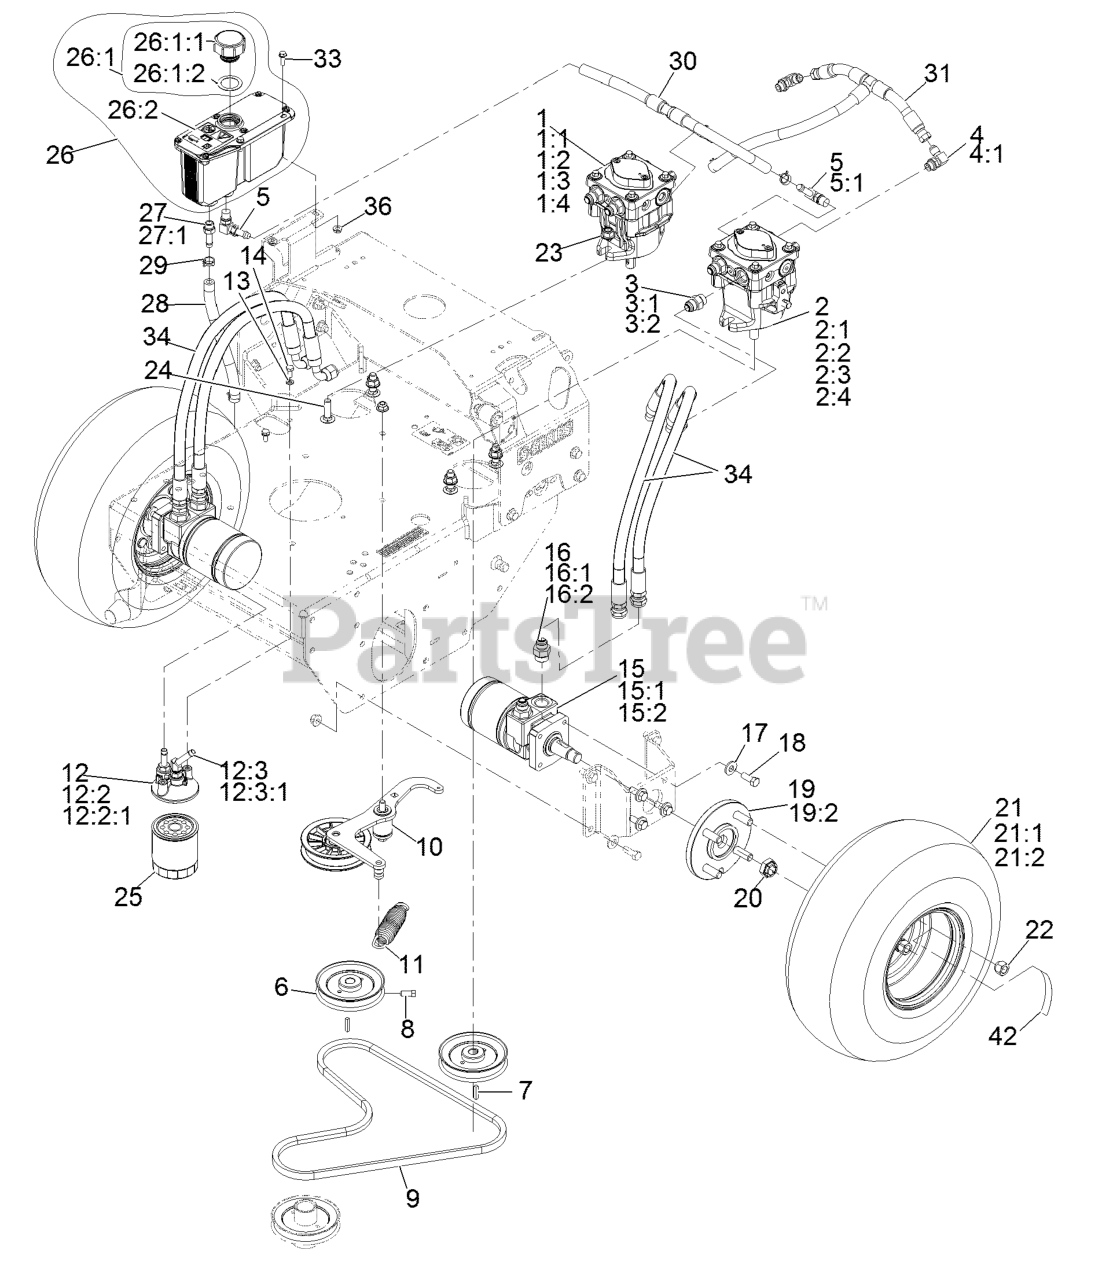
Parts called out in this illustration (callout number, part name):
1	RH HYD Pump ASM
1:1	Input Shaft Kit
1:2	Bearing-Thrust
1:3	Cylinder Block Kit
1:4	Seal Overhaul Kit
2	LH HYD Pump ASM
2:1	Input Shaft Kit
2:2	Bearing-Thrust
2:3	Cylinder Block Kit
2:4	Seal Overhaul Kit
3	Adapter-Straight
3:1	O-Ring-SAE #8
3:2	O-Ring-37 Flare #8
4	Fitting-Elbow, 90 DEG
4:1	O-Ring
5	Fitting-Elbow, 90
5:1	O-Ring
6	Sheave ASM
7	Key-5Mm X 5Mm X 25Mm
8	Screw-Set, SQH 5/16-18 X 3/4
9	Belt
10	ASM, Pump Idler
11	Spring-Extension
12	ASM, Filter Head
12:2	Adapter-Straight
12:2:1	O-Ring
12:3	Fitting-Barbed, 45 DEG
12:3:1	O-Ring
13	Washer-Lock 1/4 Heavy
14	Screw-HH 1/4-20 X 5/8
15	HYD Motor ASM
15:1	Seal Kit
15:2	Bearing And Seal Kit
16	Adapter-Straight
16:1	O-Ring
16:2	O-Ring-37 Flare #8
17	Washer-Spring Disc 3/8
18	Screw-HH 3/8-16 X 1
19	Wheel Hub ASM
19:2	Stud-Wheel
20	Nut-Lock
21	Wheel And Tire ASM
21:1	Tire-Turfmaster
21:2	Rim-Wheel
22	Nut-Lug 1/2-20
23	Nut-HF, NI
24	Bolt-Carriage 7/16-14 X 1 1/2
25	Element, Oil Filter
26	ASM, HYD Reservoir
26:1	Reservoir-HYD
26:1:1	Cap-Reservoir, HYD
26:1:2	Gasket-Cap
26:2	Decal-Warning
27	Adapter-Straight
27:1	O-Ring
28	Hose-Charge
29	Clamp-Hose 11/16
30	Hose-Case Drain
31	Hose-Charge
33	Screw-Machine 1/4-20 X 3/4
34	HYD Hose ASM
36	Nut-Whizlock 1/4-20
42	Decal-Torque Wheel Lug-Hub
